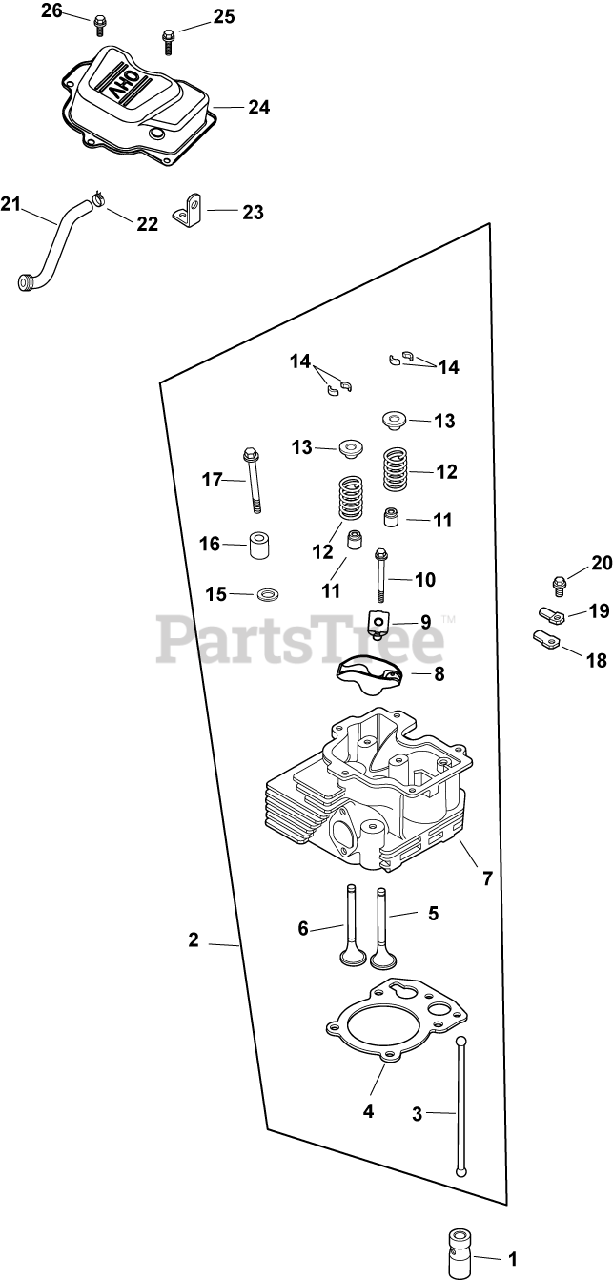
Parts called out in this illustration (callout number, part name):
1	LIFTER, HYDRAULIC VALVE-USE 25 351 10-S
2	KIT, CYLINDER HEAD
3	ROD, PUSH
4	GASKET, CYLINDER HEAD
5	VALVE, EXHAUST
6	VALVE, INTAKE
7	KIT, HEAD, CYLINDER
8	ARM, ROCKER
9	PIVOT, ROCKER ARM
10	SCREW, FLG M6X1.0X34
11	SEAL, VALVE STEM - (#2503214S)
12	SPRING, VALVE
13	RETAINER, VALVE SPRING - USE 25 173 28-S
14	KIT, RETAINER
15	WASHER, FLAT 13/32"
16	SPACER, HEAD BOLT EXHAUST PORT
17	SCREW, CYLINDER HEAD (M10 X 80)
18	REED, BREATHER
19	RETAINER, REED
20	SCREW, FLG THD FRM M5X.8X10
21	HOSE, BREATHER
22	CLAMP, HOSE (KM)-USE 25 237 31-S
24	COVER, ROCKER
25	SCREW,FLG THD FRM M6X1.0X20-(#25086396S)
26	SCREW,FLG THD FRM M6X1.0X16-(#25086397S)
2535714-S	Lubricant, Camshaft/Lifter (0.25 oz.)
